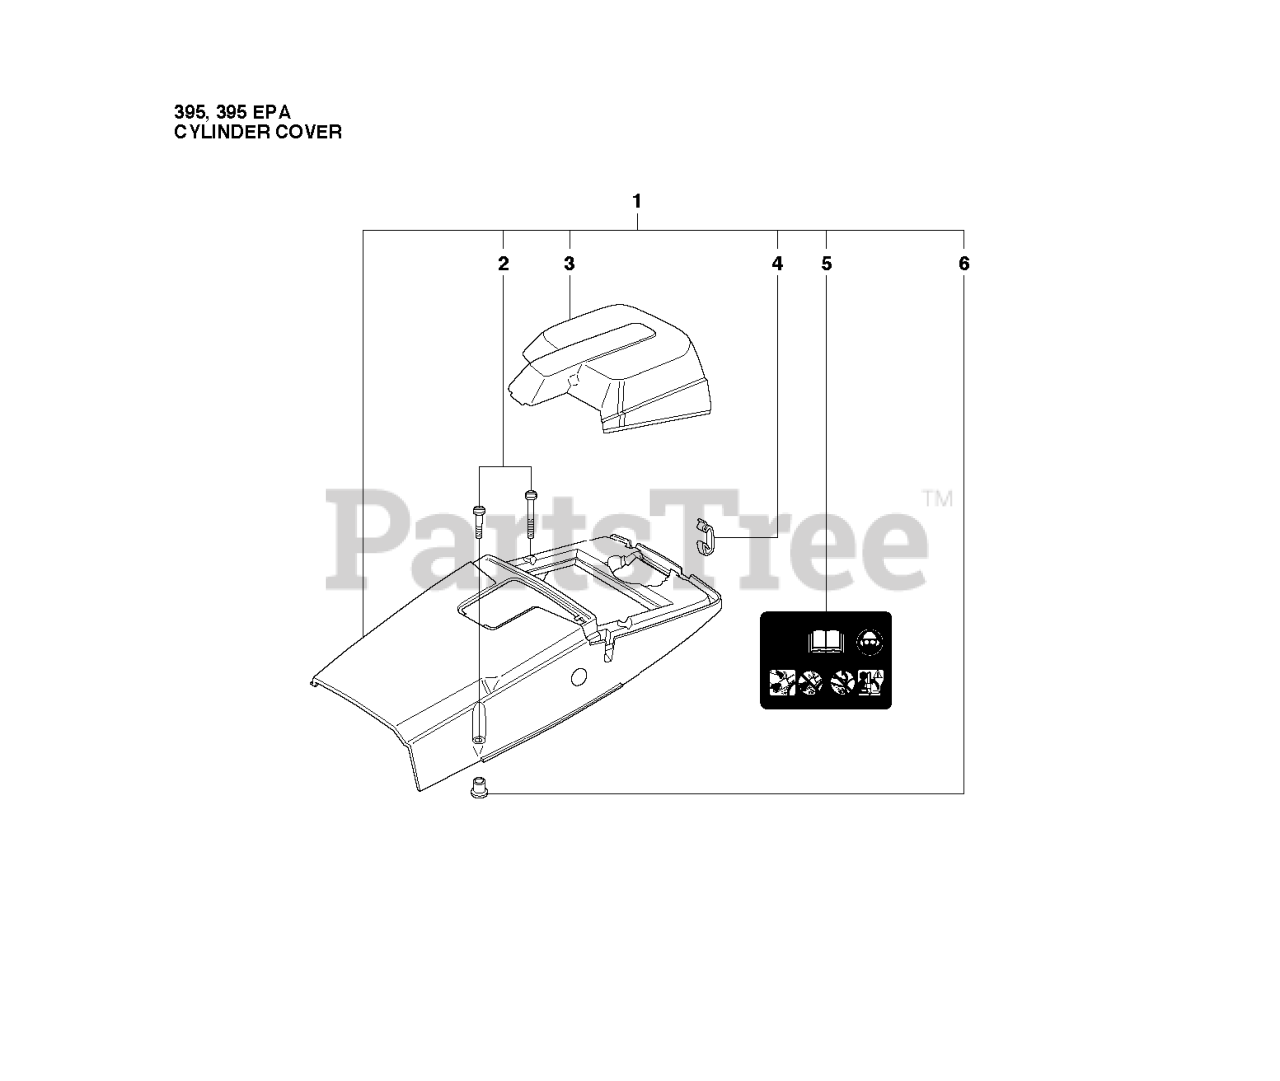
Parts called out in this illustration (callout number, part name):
1	CYLINDER COVER
2	SCREW
3	AIR FILTER COVER
